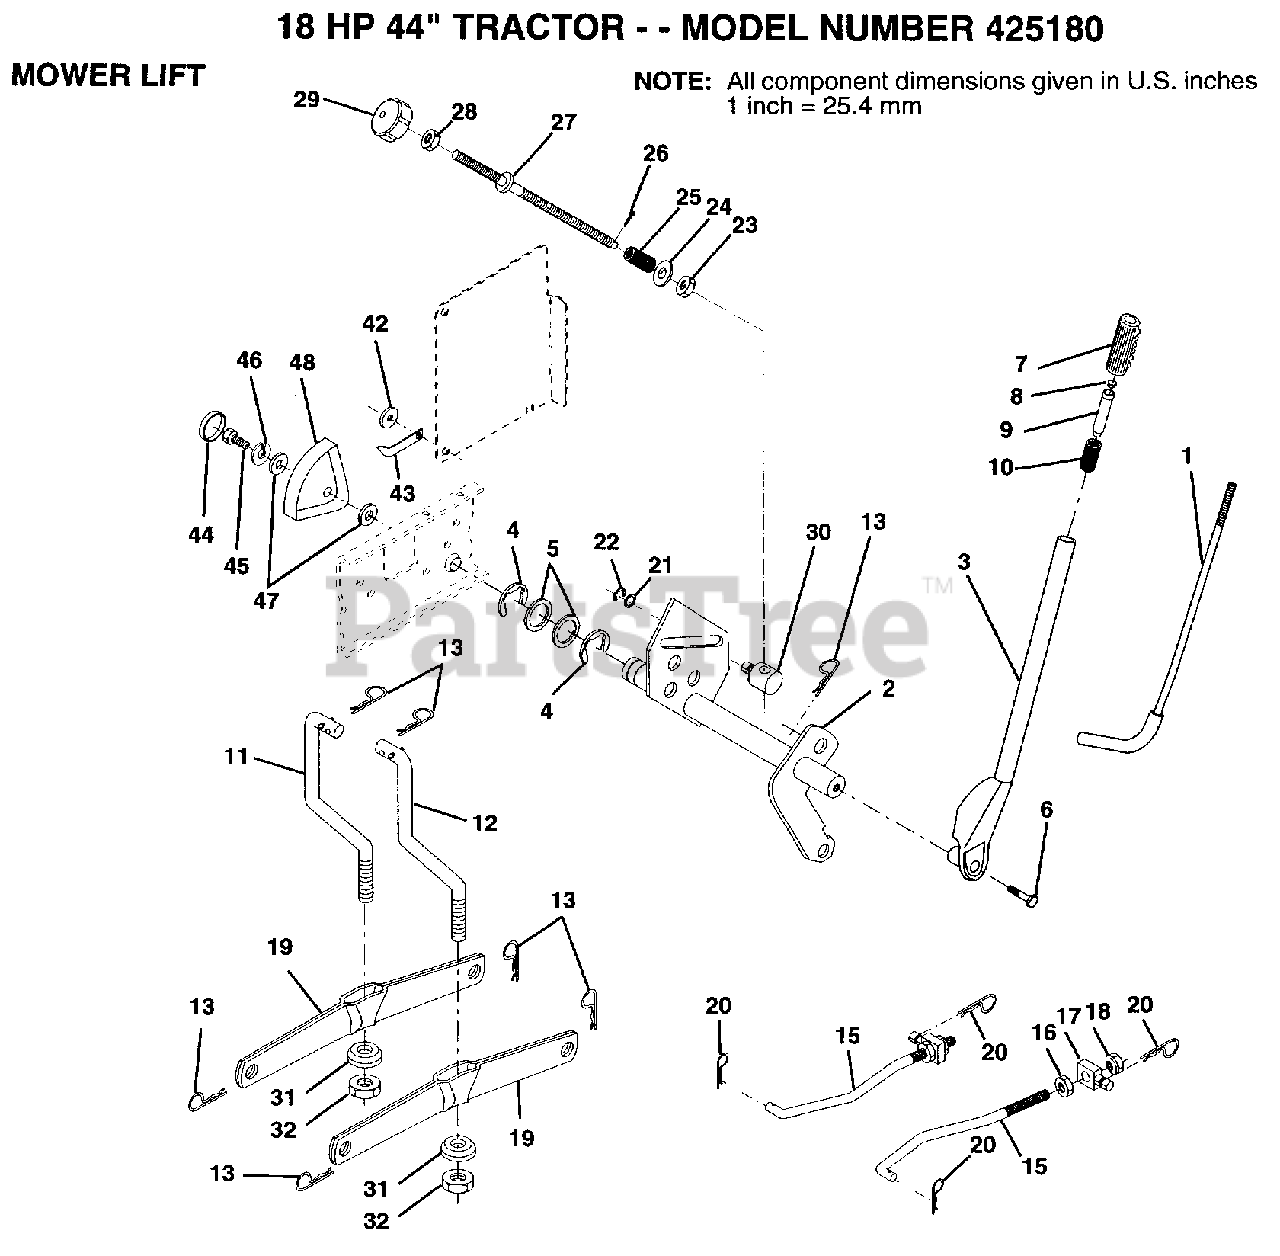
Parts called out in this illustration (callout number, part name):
1	LEVER ROD LT
2	SHAFT LIFT W/IND
4	E-RING
5	WASHER
6	"BOLT,HEX"
7	GRIP
10	SPRING T
11	LINK LIFT LH
12	LINK LIFT RH
15	LINK.FRONT
16	NUT
17	TRUNION
18	NUT.LK.W/WSH.1/2.
19	ARM SUSP REAR
20	RETAINER.SPRING
21	WASHER
22	KLIP RING
23	NUT T
24	WASHER
25	SPRING T
27	ROD LIFT LT
28	NUT
29	KNOB INF 3/8-16
30	TRUNION LT
31	BEARING PVT LH
32	NUT.LOCK.3/8-24
42	WASHER T
43	POINTER HGT IND
44	"PLUG,HOLE"
46	LOCKWASHER
47	WASHER
48	HEIGHT INDICATOR
